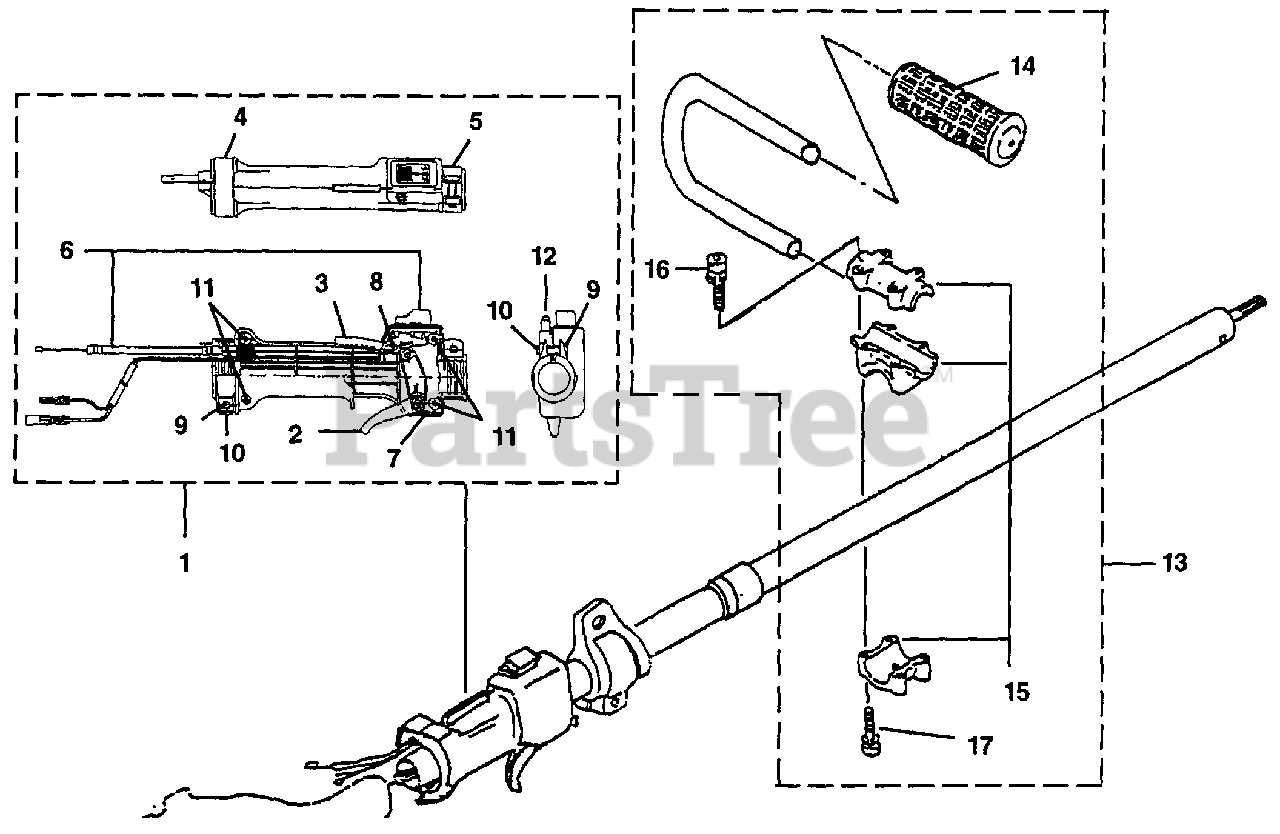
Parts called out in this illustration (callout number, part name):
1	CONTROL LEVER ASSEMBLY
2	THROTTLE-Trigger
3	LATCH-Trigger
6	CONTROL CABLE ASSEMBLY
11	SCREW-Tapping
12	LOCK-Throttle Start
13	HANDLE ASSEMBLY
15	HANDLE-Bracket Assembly
16	BOLT-Socket Hd (M5 x 25 SW)
17	BOLT-Socket Hd (M5 x 25 SW)
